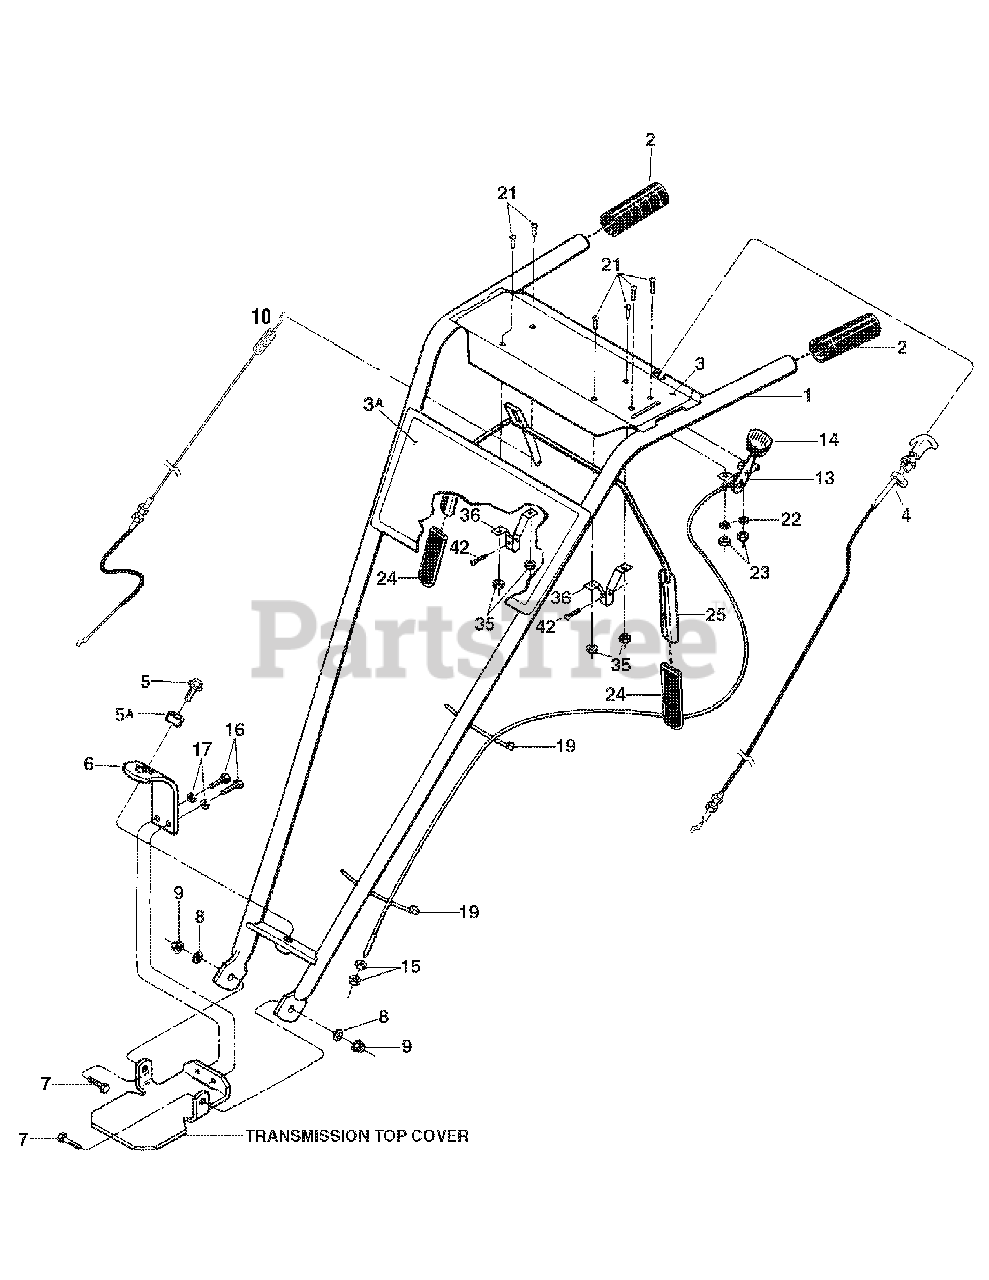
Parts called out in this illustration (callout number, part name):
1	Handlebars
3	De cal, Control Panel
3A	Decal, Model Name/Logo
4	Reverse Clutch Control Cable
5	Height Adjustment Screw
5A	Washer, Keyed
6	Bracket, Handlebar Height Adjustment
7	Hex Hd. Screw, 3/8-16 x 1
8	Washer, Plain (flat) 3/8, S.A.E.
9	Hex Locknut, 3/8-16
10	Cable, Forward Clutch Control
13	Wheel Gear Control and Cable Assy
14	Knob, Wheel Gear Control Lever
15	Hex Nut, 5/16-24
16	Hex Hd. Screw, 3/8-16 x 5/8
17	Lockwasher, 3/8
19	Cable Ties, Plastic
21	Round Hd. Screw, #10-32 x 1/2
22	Lockwasher, #10
23	Hex Nut, #10-32
25	Bail w/ Grips, Forward Clutch Control .
36	Bracket, Bail Support
42	Hex Flange Screw, self-tapping, 1/4-20 x 1/2"
